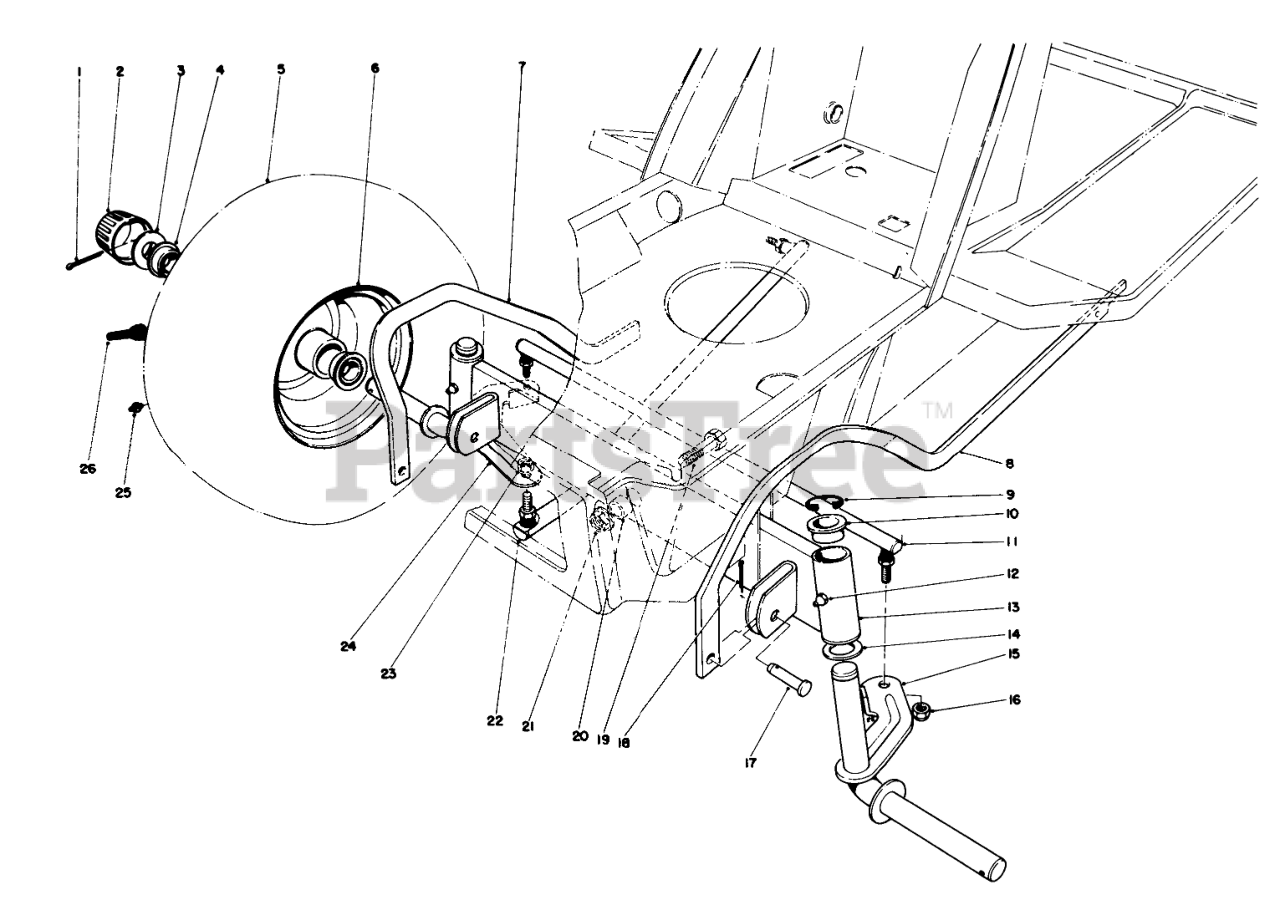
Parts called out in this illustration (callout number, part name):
1	PIN-COTTER
2	Cap-Hub
3	WASHER-PLAIN
4	Bearing
5	TIRE-FRONT
6	FRONT WHEEL
7	RH DECK PARALLEL LINK R
8	LH DECK PARALEL LNKR
9	E-RING
10	BEARING-FLANGE
11	Tie Rod Steering
12	GREASE FITTING
13	Front Axle (Incl. Ref. #10)
14	WASHER-THRUST
15	Spindle L.H.
16	NUT-LOCK, NI
17	PIN-CLEVIS
18	PIN-COTTER
19	SCREW-HH
20	SPACER-AXLE, FRONT
21	NUT-HF
22	STEERING ARM B
23	NUT-HEX
24	SPINDLE WA RH B
25	FITTING-GREASE
26	STEM-VALVE
